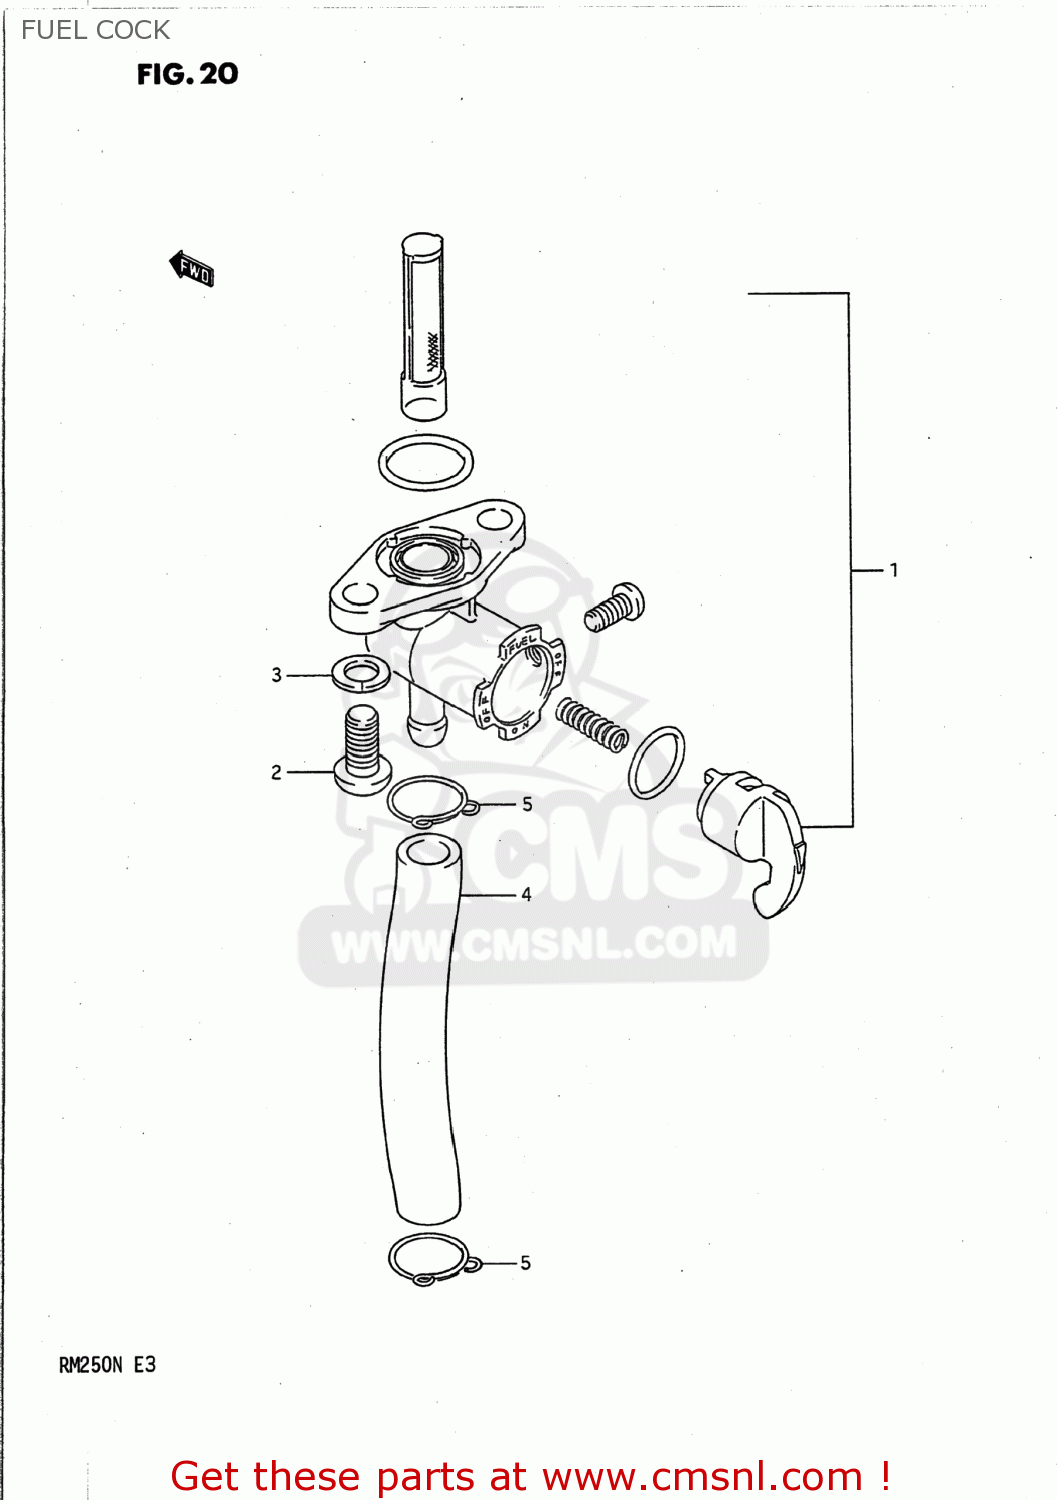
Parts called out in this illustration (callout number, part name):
1	COCK ASSEMBLY,FUEL
2	SCREW
3	WASHER,LOCK
4	HOSE (6.5X11.5X300)
5	CLIP
